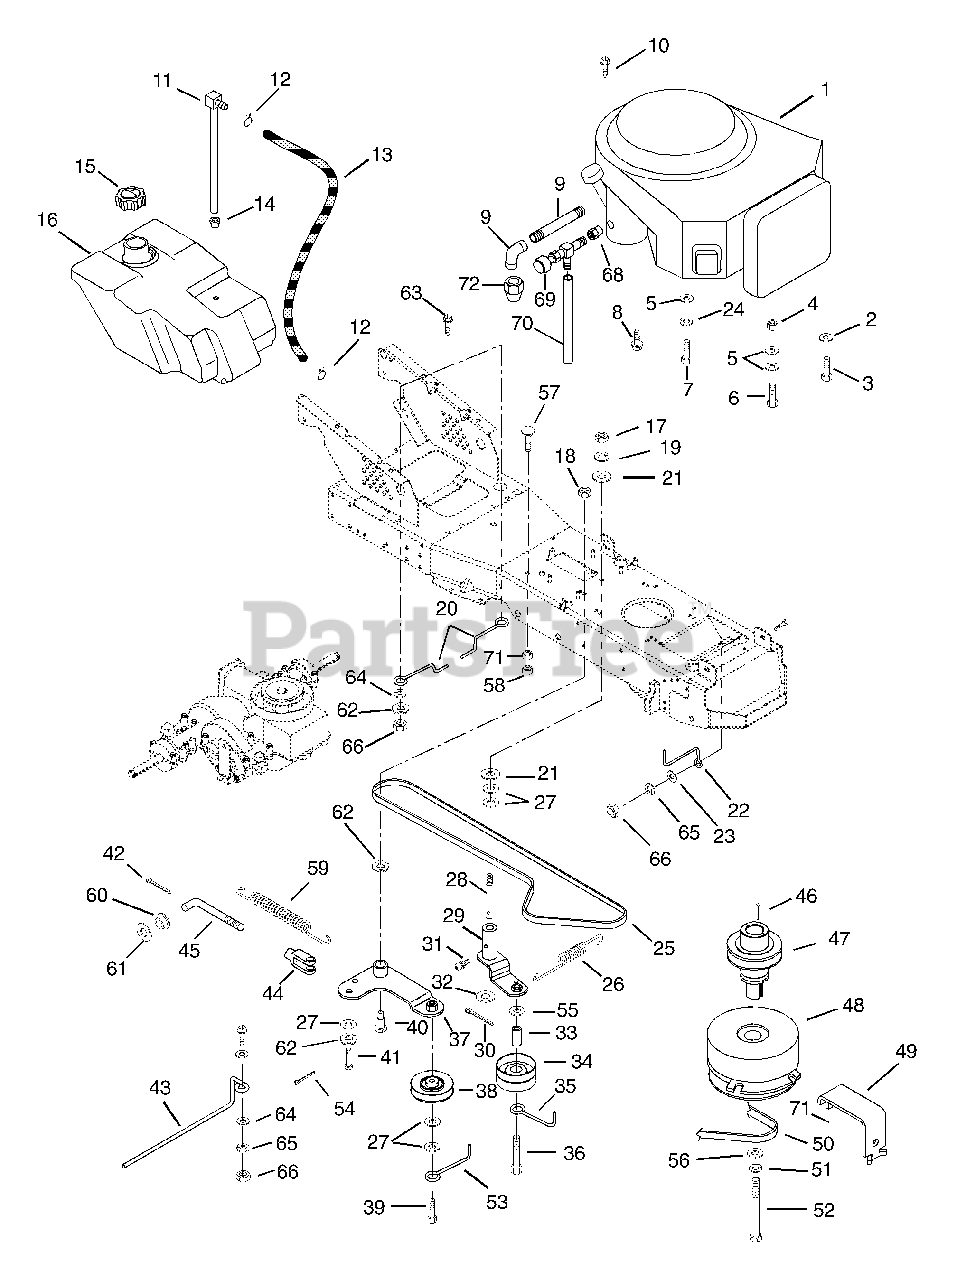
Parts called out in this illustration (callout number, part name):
1	ENGINE BRIGGS 16HP TWIN
1	ENGINE TECUMSEH 13HP VERT
1	BRIGG 15HP W/9AMP CHARGING
1	ENG- 15.0 KOHLER OHV PS-41531
2	@WSHR-LK-EXT.391X.628X.036YWZC
3	@SCR-TAP .38-16X1.25 HWH TR YZ
4	@NUT-LK-CTR .31-18 YWZC
5	WSHR-FL-STL .328X.875X.062YWZC
6	@BLT-HEX .31-18X1.50 GR5 YWZC
7	BLT, HEX M8-1.25X25 GR8.8YWZC
8	NIPPLE
9	ELBOW .375-18 NPTF
10	@SCR-TAP .31-18X.75 HWH TR YWZ
11	TANK FITTING
12	CLAMP-HOSE WIR.490/.510X.092#8
13	HOSE- FUEL LINE 36.00"
13	HOSE- FUEL LINE 48.00"
13	HOSE- FUEL LINE 50.00"
14	BSHG-FLG .375 X 1.062 X .625 R
15	FUEL CAP
16	FUEL TANK
17	@NUT-HEX .38-16 YWZC
18	@NUT-LK-CTR .38-16 YWZC
19	@WSHR-LK .38X.094 REG YWZC
20	BELT FINGER
21	@WSHR-FL-STL.438X1.00X.083 YWZ
22	BELT FINGER
23	@WSHR-FL-STL.312X.734X.065 YWZ
24	@WSHR-LK .31X.078 REG YWZC
25	V-BELT, 4L-WRAPPED
26	SPRING, EXT
27	WSHR-FL-STL .390X.75X.125 YWZC
28	SHOULDER STUD
29	ARM - IDLER PIVOT
30	@PIN-CTR .18X1.25 EXTPRSQCT YZ
31	FTG-LUBE .25-28X.256 YWZC
32	WSHR-FL-STL .52X.827X.062 YWZC
33	TUBE .380 X .625 X 1.620
34	IDLER-FLAT 3.25 X .38 NWHAMSHR
35	FINGER - BELT
36	@BLT-HEX .38-16X3.50 GR5 YWZC
36	@BLT-HEX .38-16X3.75 GR5 YWZC
37	IDLER PIVOT ARM
38	IDLER-V 3X.38
39	@BLT-HEX .38-16X1.75 GR5 YWZC
40	BLT-SHLDR .38-16X1.25
41	PIN-CLEV .312X.822 HDND PL
42	@PIN-CTR .09X.75 EXTPRSQCT YWZ
43	FINGER - BELT
44	YOKE, .312-24 X 2.25
46	KEY-SQ .25 X 1.25 X .25 SAE
47	SHEAVE EXTENSION SHAFT-GEAR
47	SHEAVE EXTENSION SHAFT- HYDRO
48	ELECTRIC CLUTCH/BRAKE (3.4AMP)
48	CLUTCH, ELECTRIC - WARNER
48	ELECTRIC CLUTCH/BRAKE(1.8AMP)
49	ANCHOR - CLUTCH
50	V-BELT, 4L-RAW EDGE
51	WSHR-LK .438X.133 HVY YWZC
52	BLT-HEX .44-20X4.00 GR5 YWZC
52	BLT-HEX .44-20X4.50 GR8 YWZC
53	FINGER - BELT
54	PIN-HAIR INT .08X.18X1.18 YWZC
55	WSHR-FL-STL .390X.88X.18 YWZC
56	WSHR-FL-STL.463X1.375X.25 YWZC
57	BLT-RDHDSQNK .31-18X1.0 SHTYZ
58	@NUT-LK-CTR .31-18 YWZC
59	SG-TENS .105X.85X5.00 WLD 40
60	BSHG-FLG .320X.620X.312 NY
61	WSHR-FL-STL .505X.880X.072 YWZ
62	WAVE WASHER .531X.781X.125FH
63	BLT-RDHDSQSHK.31-18X.75 GR2 YW
64	@WSHR-FL-STL.344X.688X.065YWZC
65	WSHR-LK .312X.097 HVY YWZC
66	@NUT-HEX .31-18 YWZC
67	J-CLAMP
68	ADAPTER, OIL DRAIN
69	COCK, OIL DRAIN
70	TUBE OIL DRAIN
71	NUT-LK-NYL.312-18 PL
72	ADAPTER, OIL DRAIN
